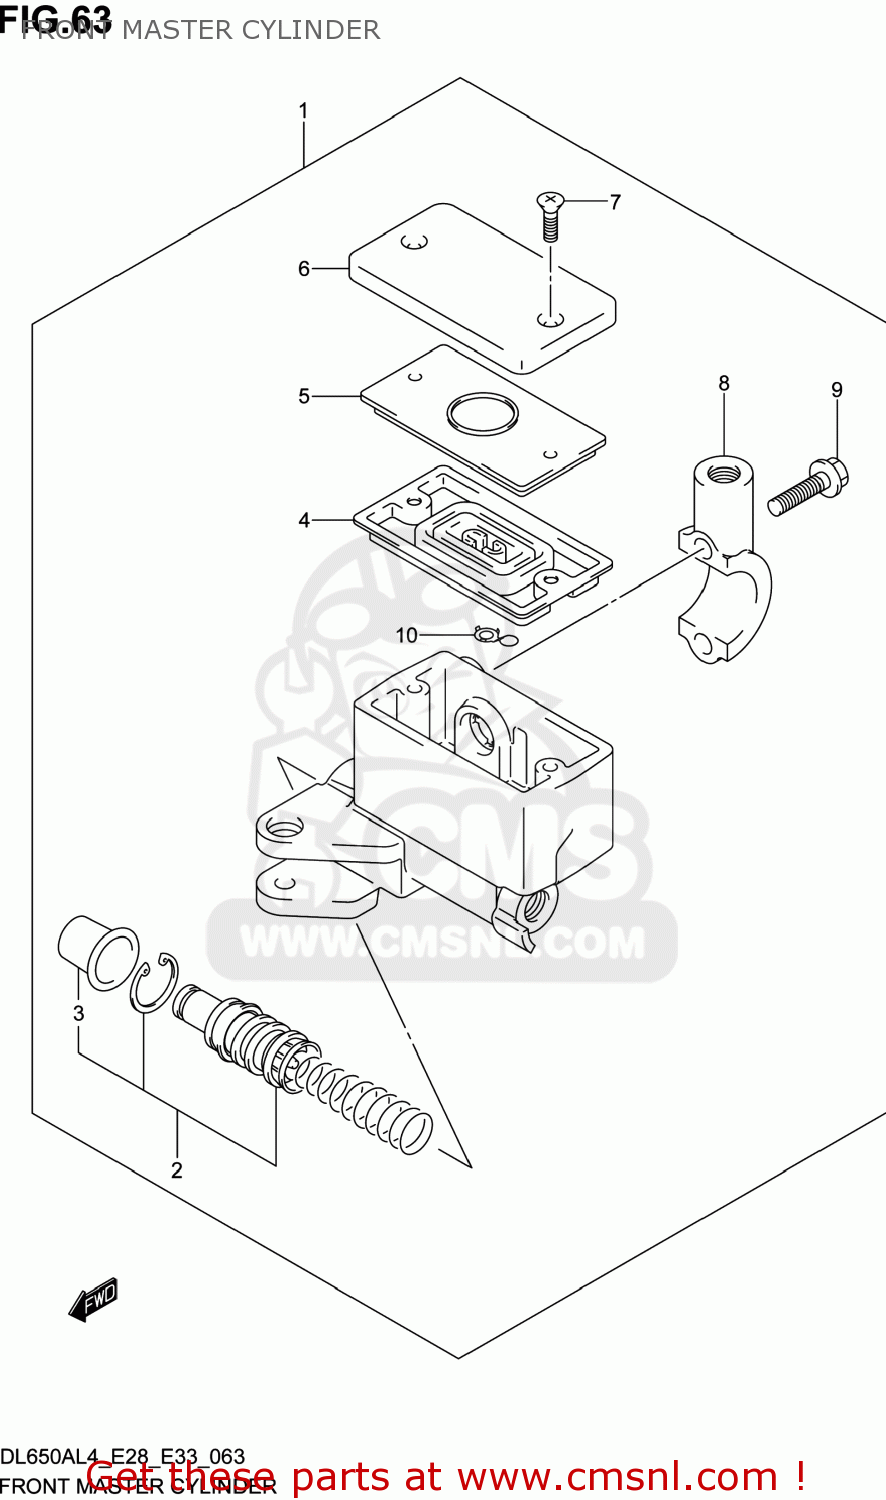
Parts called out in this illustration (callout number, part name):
1	CYLINDER ASSY,FR MASTER
2	PISTON & CUP SET
3	BOOT
4	5
5	PLATE,DIAPHRAGM
6	CAP
7	SCREW
8	HOLDER
9	BOLT(6X22)
10	PROTECTOR
